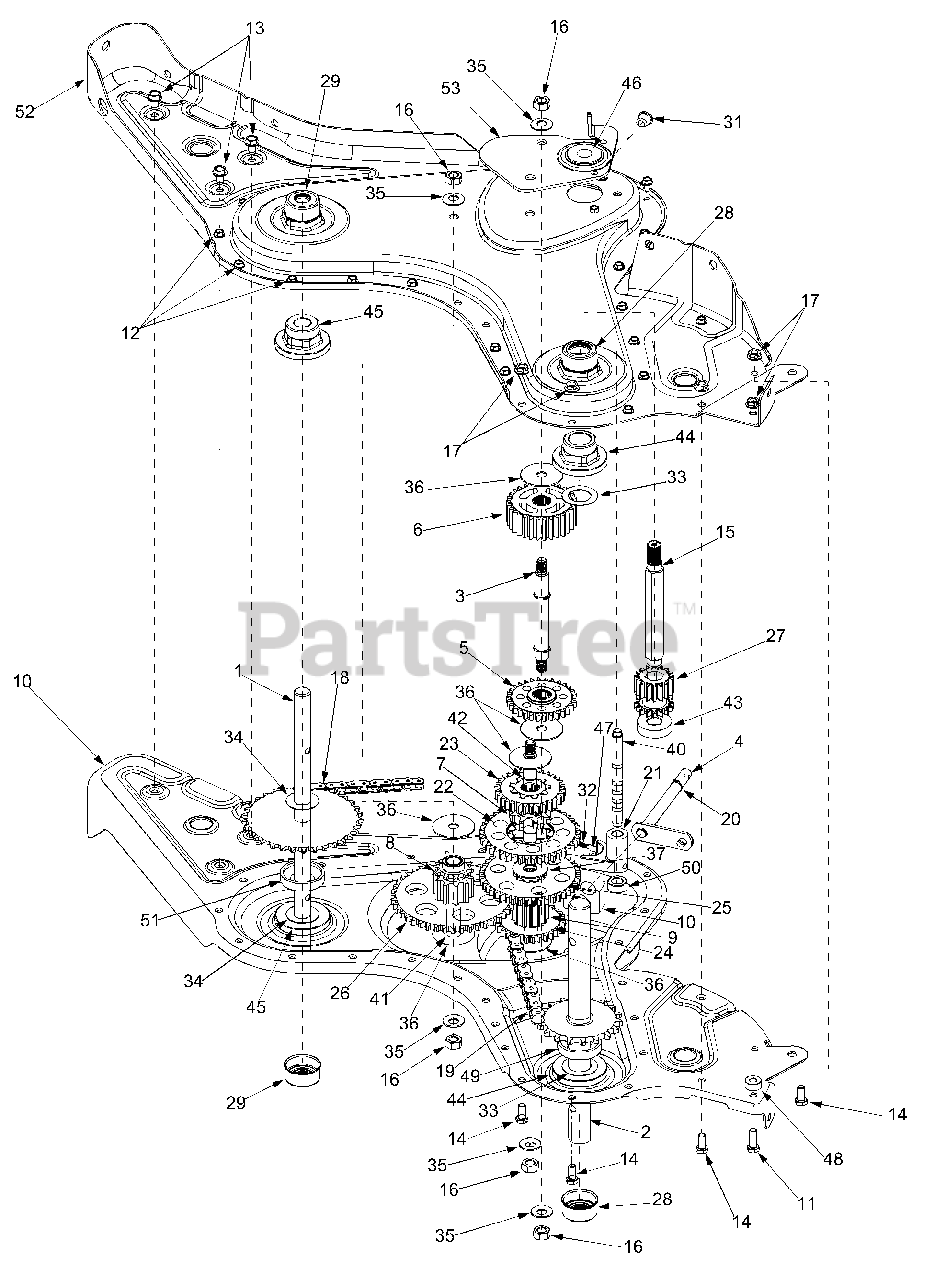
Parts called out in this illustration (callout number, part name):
1	Wheel Shaft Ass'y 33T
2	Tine Shaft Ass'y: 18T
3	Jack Shaft Ass'y
4	Input Shaft Ass'y
5	Rev. Idler Gear Ass'y: 30T
6	Tine Idler Gear Ass'y: 30T
7	Tine Input Sprocket Ass'y: 9T
8	Wheel Input Sprocket Ass'y: 10T
9	Gear Ass'y: 11T
11	Hex Bolt 5/16-18 x 1" Lg.
12	Hex S-Tap Scr. 1/4- 20 x.5"
13	Hex S-Tap Scr. 5/16-18 x.625"
14	Hex Bolt 5/16-18 x.75"
15	Input Shaft
16	Hex Nut 7/16-20
17	Flange Nut 5/16-18
18	#420 Chain 1/2 Pitch x 50 Links
19	#50 Chain 5/8 Pitch x 54 Links
20	Snap Ring
21	Shifting Fork
22	Spur Gear 44T
23	Spur Gear 30T
24	Spur Gear 30T
25	Spur Gear 44T
26	Spur Gear 44T
27	Spur Gear 16T
28	Seal 1.0 Shaft
29	Seal.75 Shaft
31	Taper Cap Ring
32	Compression Spring.50" Leg.
33	Thrust Wash. 1.03" I.D. X. 1.62"
34	Fl-Wash.76" I.D. x 1.5" O.D.
35	Bell-Wash .45" I.D. x 1.0"
36	Thrust Wash. .445 x 1.92 x .060
37	Fl-Wash. .635" I.D. x 1.59 O.D.
40	Detent Shaft 1/2" Dia.
41	Jack Shaft .625 x 2.385
42	Jack Shaft .625 x 5.0
43	Ball Bearing
44	Flange Bearing 1.0 x 2.5 x 1.38
45	Flange Bearing .75 x 2.5 x 1.38
46	Ball Bearing .6692 x 5745 x .466
47	Detent Ball .250
48	Spacer .315
49	Spacer 1.0 I.D x 2.0 O.D. x .440
50	Spacer .505 I.D. x .88 O.D. x .440
51	Spacer .75 x 2.0 x .50
53	Gear Positioner Bracket
